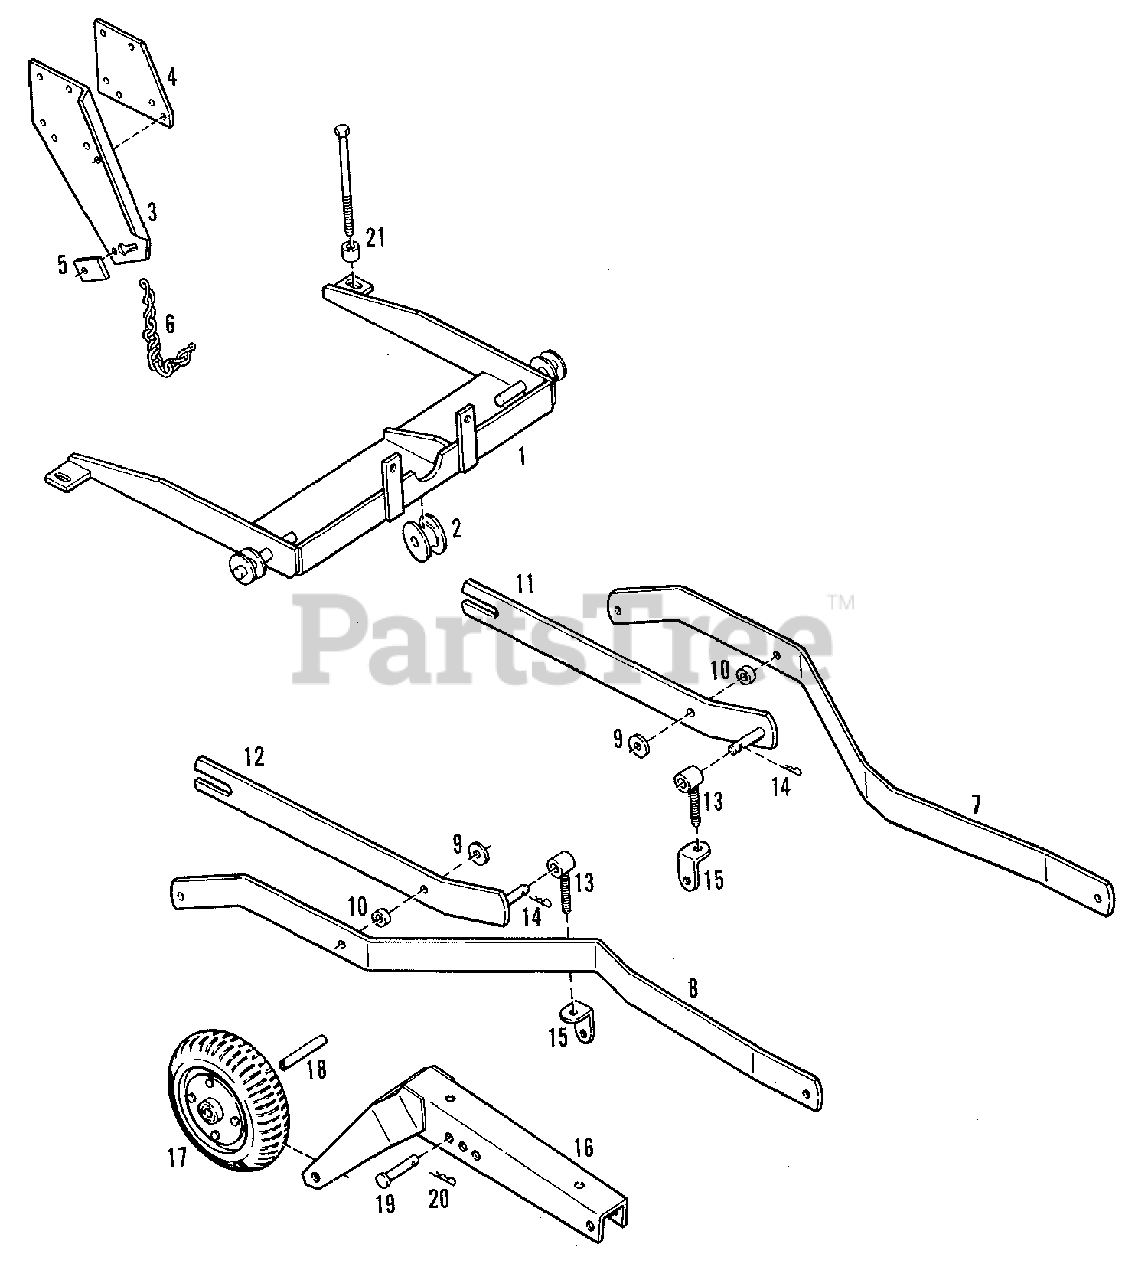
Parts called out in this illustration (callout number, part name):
1	BRACKET ASSEMBLY, Belly Mouting
2	SHEAVE, Chain
2	CAPSCREW, 1/2NC x 3
2	NUT, Lock, 1/2NC
3	CAPSCREW, 3/8NC x 1-1/2
3	LOCKWASHER, 3/8
4	PLATE, Lift Arm
5	TAB, Chain Lock
5	CAPSCREW, 1/4NC x 1
5	LOCKWASHER, 1/4
6	CHAIN, Lift, 42"
7	BAR, Linkage, L.H.
7	CAPSCREW, 1/2NC x 2
7	NUT, Lock, 1/2NC
8	BAR, Linkage, R.H.
8	CAPSCREW, 1/2NC x 2
8	NUT, lock, 1/2NC
9	WASHER, Flat, Spindle
10	BUSHING, Pivot
11	BAR ASSEMBLY, Linkage, L.H.
12	BAR ASSEMBLY, Linkage, R.H.
13	SCREW, Leveling
14	PIN, Hair, Cotter, No. 6
15	LINK, Leveling
15	CAPSCREW, 1/2NC x 2
15	NUT, Lock, 1/2NC
16	ARM ASSEMBLY, Guage Wheel
16	CAPSCREW, 1/2NC x 3-1/2
16	NUT, Lock, 1/2NC
17	TIRE & WHEEL, Gauge
18	BUSHING, Guage Wheel
18	CAPSCREW, 1/2NC x 4-1/2
18	NUT, Lock, 1/2NC
19	PIN, Clevis, 1/2 x 3
20	PIN, Hair, Cotter, No. 4
21	SPACER, Mounting
21	CAPSCREW, 1/2NC x 7
